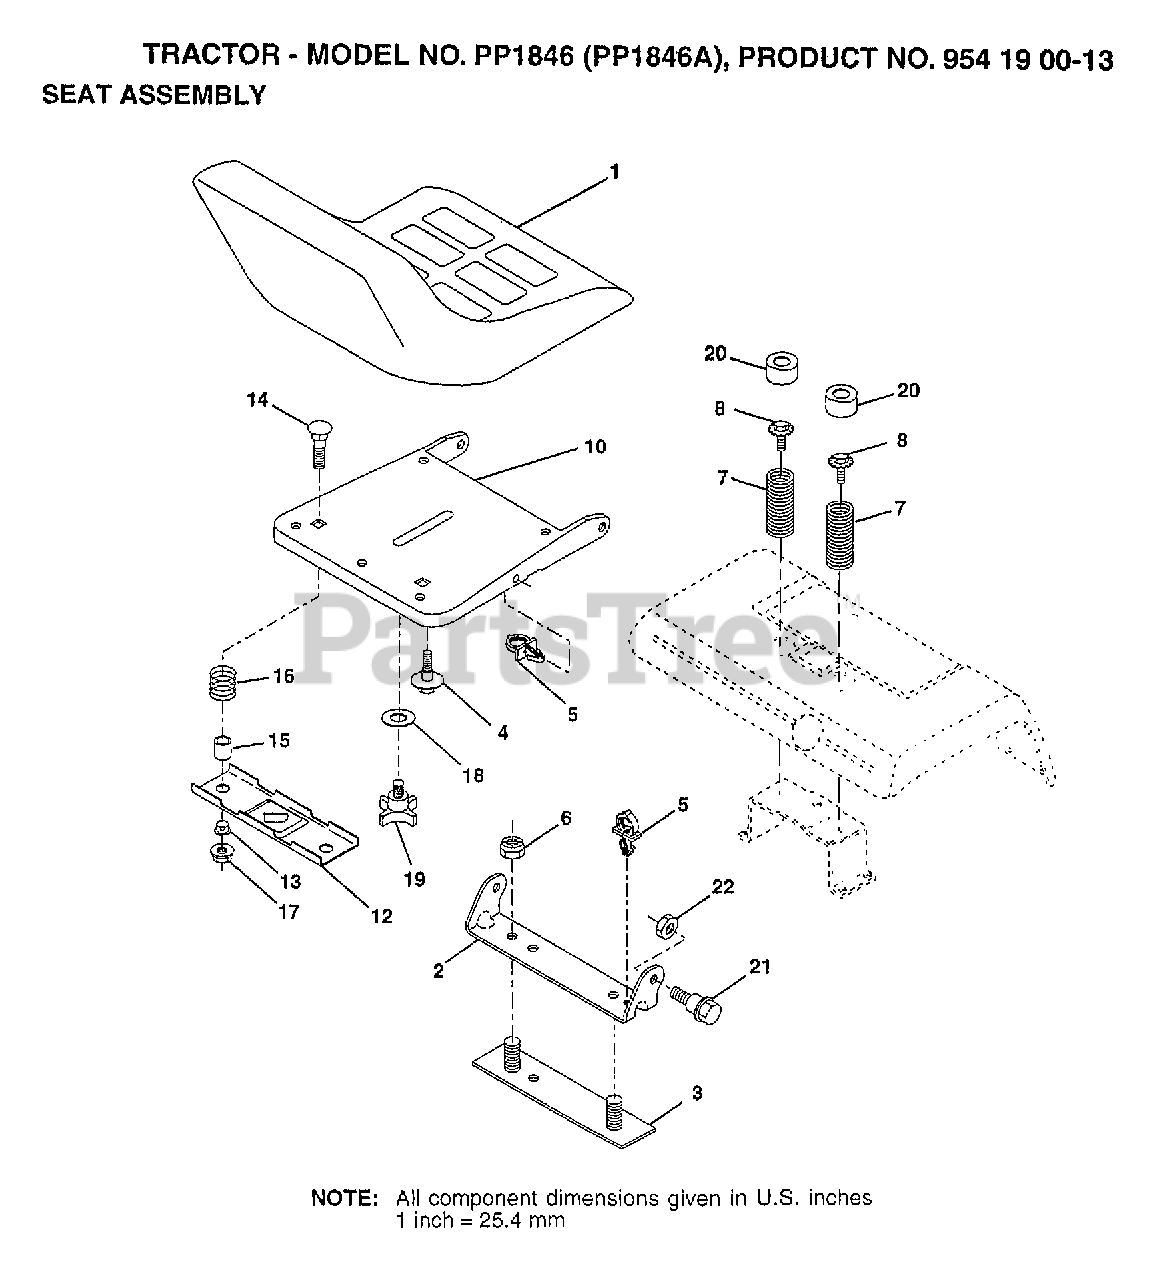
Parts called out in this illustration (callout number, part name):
2	BRACKET PVT SEAT
3	STRAP ASM FENDER
4	"BOLT,SHOULDER"
5	CLIP.PUSH-IN.HING
7	SPRING COMPRESSIO
8	BOLT.5/16-18.UNC
10	PAN-SEAT
12	BRKT SWITCH
13	BUSHING
15	SPACER SPLIT
16	SPRING COMPRESSED
18	WASHER
19	"KNOB 1/2"" YT"
20	CAP SPRING
21	"BOLT,SHOULDER"
